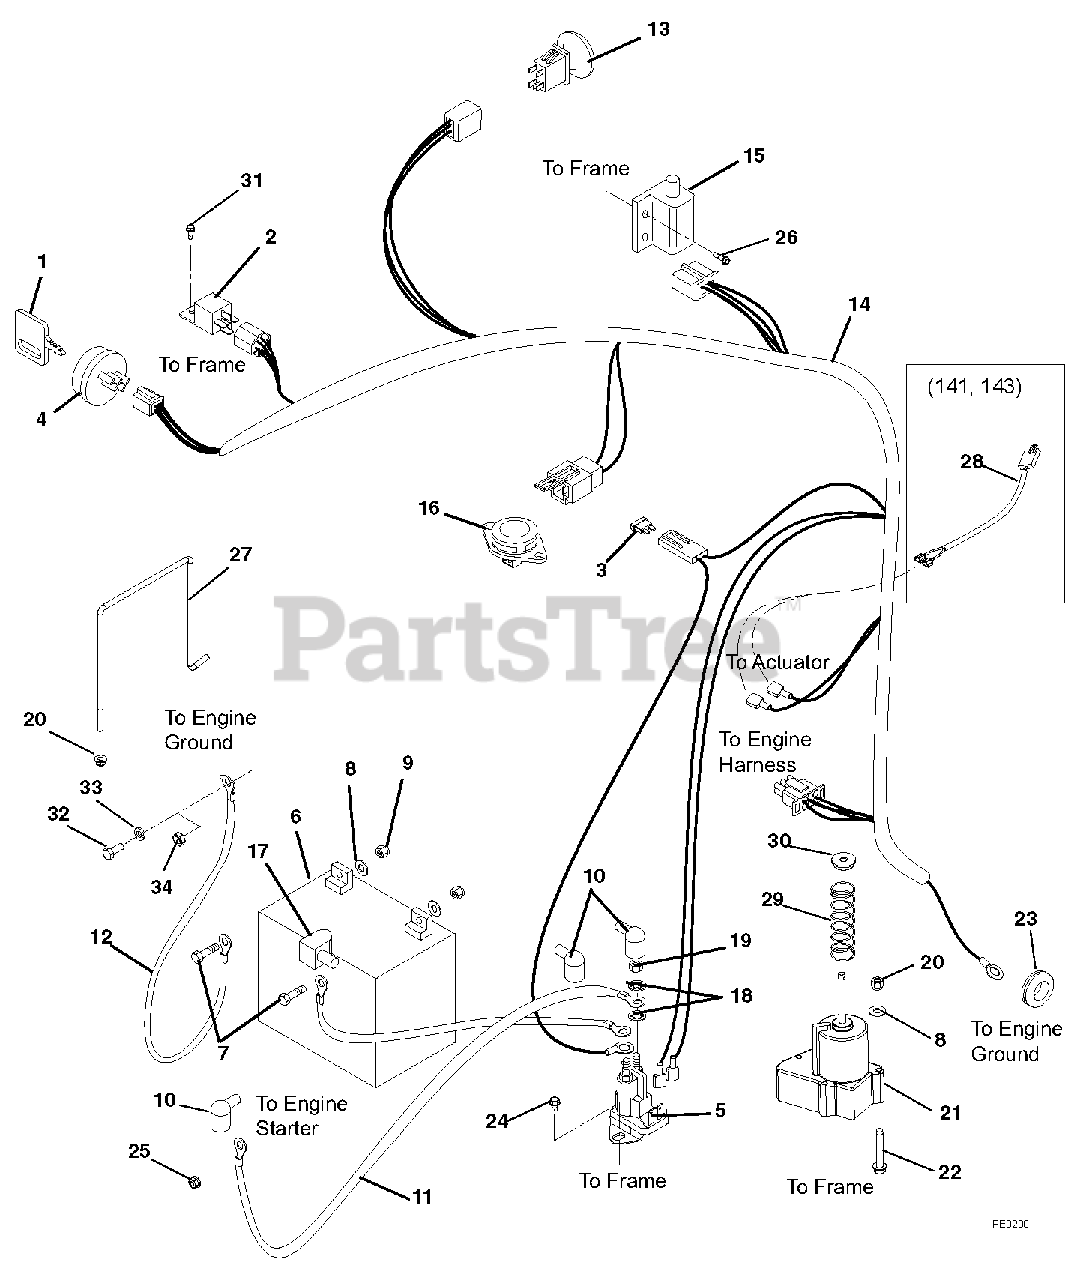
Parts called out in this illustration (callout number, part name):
2	Relay
3	Fuse, 30 AMP
4	KEYSWITCH-IGNITION 3 POS
5	Solenoid
7	Bolt, Hex .25-20 x .75 Grade 5
8	Washer, Flat Steel .281 x .62 x .065 (140)
9	Nut, KEPS .250-20
10	Boot, Eyelet Terminal
11	Cable, POS
12	Ground Cable
13	Switch, Clutch With Retainer
14	Harness, Wiring Zoom/ZT
15	Switch, Double Pole N.O. / N.O.
16	Switch, Snap Mounting (N.O.)
17	Insulator
18	Washer, Locking .31
19	Nut, Jam .31-24
20	Nut, .25-20 Nyloc Flange (140)
21	Actuator-NORAM PAC 2" (140)
22	Bolt, Hex .25-20 x 2.50 Grade 5 (140)
23	Grommet .125 x 1.000 ID
24	Screw, Tapping .250-20 x .37 Hex Washer Head
25	Nut, Locking-Top-Flange .25-20
26	Screw, 12-14 x .75 HX
27	Hold Down, Battery
28	Harness, Clutch (142, 144)
29	Spring, Compression (140)
30	Retainer, Compression Spring (140)
31	Screw, Tapping 12-24 x .50 Hex Washer Head
32	Bolt, Hex M8-1.25 x 20(144)
33	Washer, Locking .31 x .078 Regular(144)
34	Nut, Locking-Center-Jam .375-16(140, 142)
